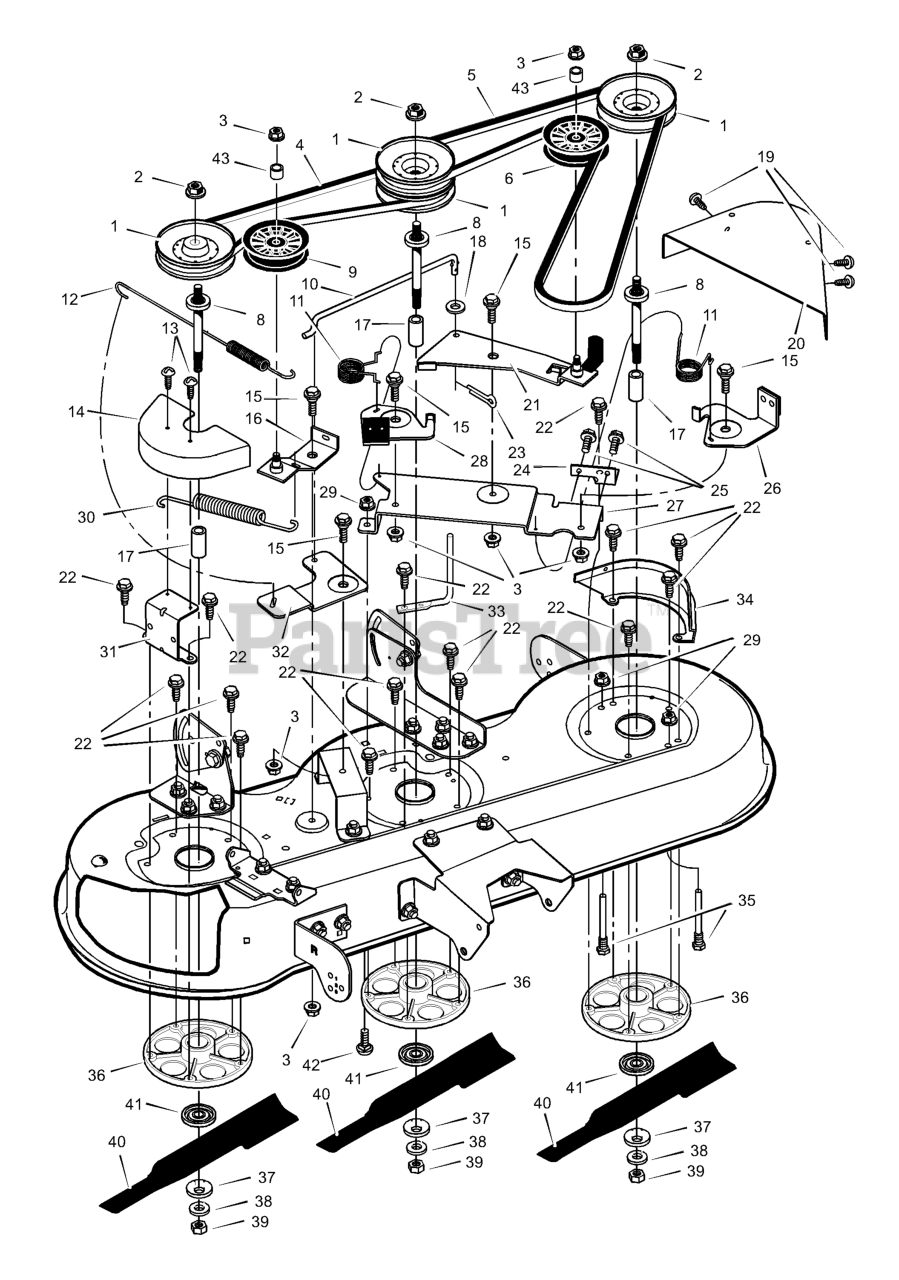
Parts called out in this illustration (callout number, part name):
1	Pulley
3	Nut
4	Belt, Secondary
5	Belt, Primary
6	Pulley, Idler
8	Jackshaft
9	Pulley, Idler
10	Link, Bell Crank
13	Screw
14	Cover, Right Pulley
15	Bolt, Shoulder
16	Arm Assembly, Idler
18	Washer
20	Cover, Left Pulley
21	Arm Assembly, Idler
22	Bolt
23	Pin, Cotter
24	Bracket, Brake Plate
26	Brake Assembly, Left
27	Plate, Brake Arm
28	Brake Assembly, Center
29	Nut, Flange
31	Bracket, Cover
32	Bell Crank
33	Guide, Belt
34	Bracket, Pulley Cover
35	Guide, Belt
36	Housing, Jackshaft
39	Nut, Blade
41	Adapter, Blade
42	Bolt, Carriage
